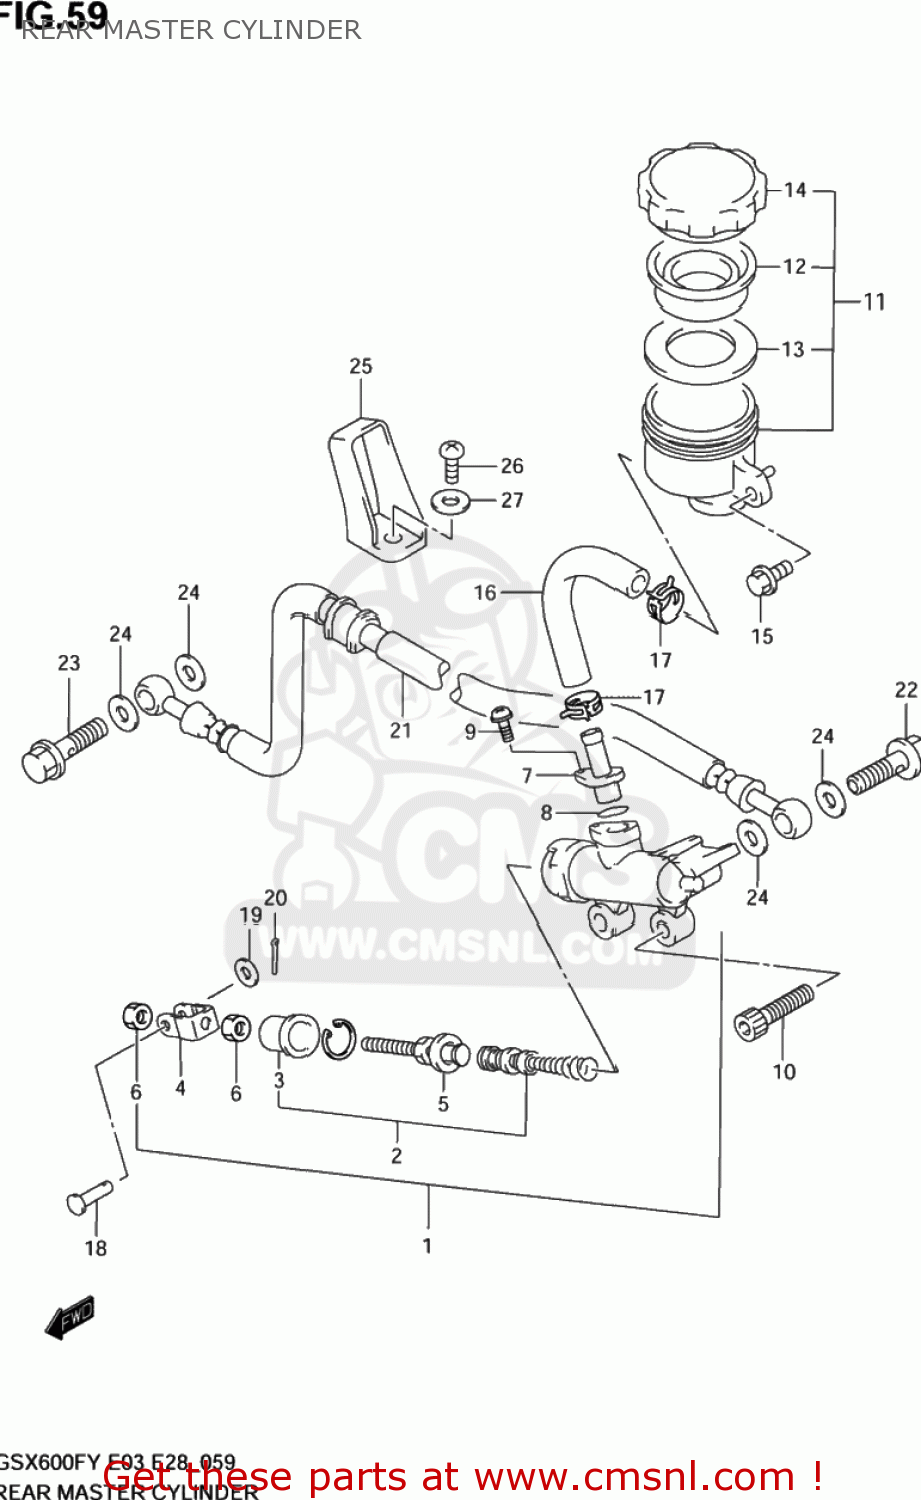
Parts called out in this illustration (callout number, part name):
1	CYLINDER ASSY,RR MASTER
2	PISTON/CUP SET
3	BOOT
4	YOKE
5	ROD,PUSH
6	NUT
7	CONNECTOR
8	O RING
9	SCREW
10	BOLT(6X16)
11	TANK ASSY,RR RESERVOIR
12	DIAPHRAGM
13	PLATE,DIAPHRAGM
14	CAP
15	BOLT
16	HOSE,RESERVOIR TANK
17	CLIP
18	PIN
19	WASHER
20	PIN
21	HOSE COMP,REAR BRAKE
22	BOLT UNION
23	BOLT UNION
24	WASHER(10X15X1.5)
25	GUIDE,RR BRAKE HOSE
26	SCREW
27	WASHER
